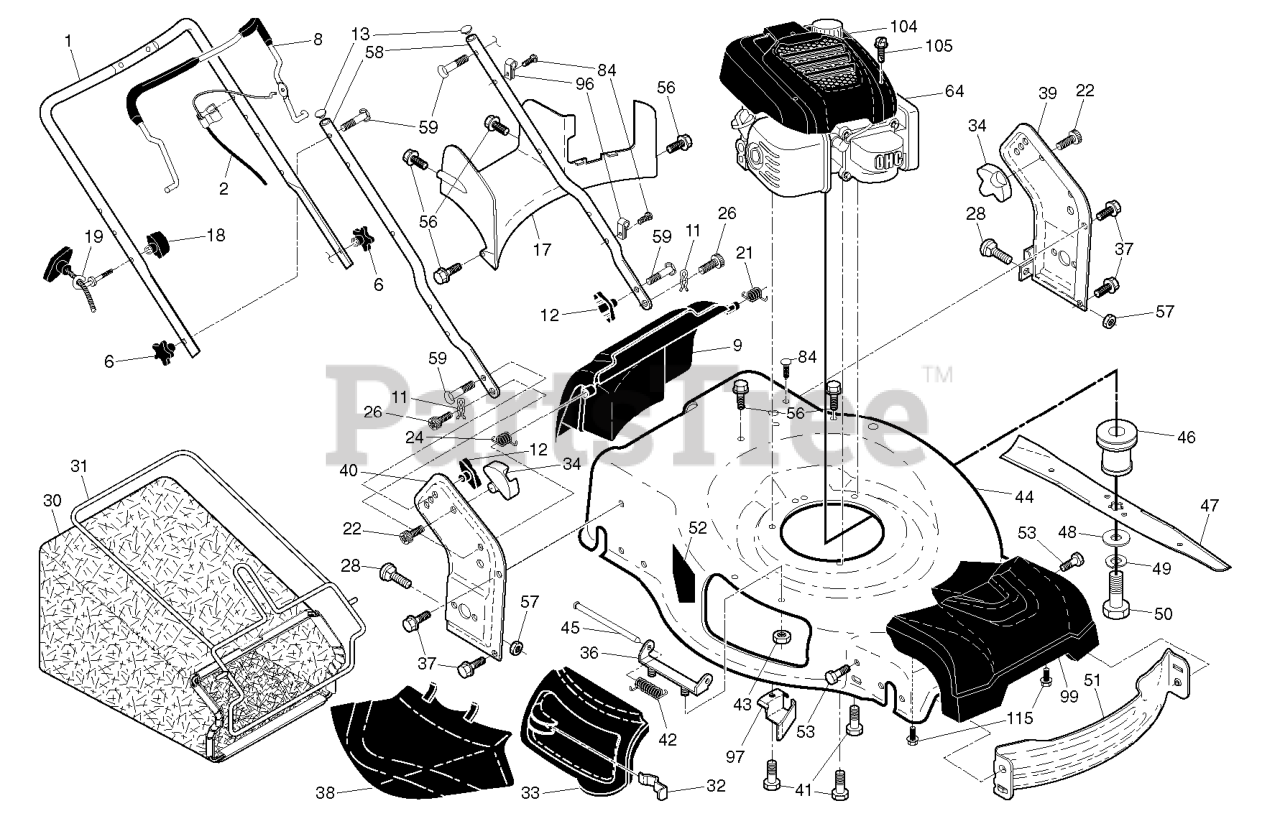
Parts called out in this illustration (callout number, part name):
1	HANDLE.UP.3POS.BS.AW2.GREY
2	CABLE.MZR.ZONE.CONTROL
6	KNOB.HANDLE.PLASTIC.STAR.BLACK
8	BAIL.OM.ERGO.BENT.MZR.ORAN.668
9	DOOR.REAR.ASM.22+.HUSQ.F/RG.CE
11	COTTER.HAIRPIN.DOOR/HANDLE.PIV
12	KNOB, DEFLECTOR
13	PLUG.PLASTIC.7/8".14-20.GAUGE
17	BAFFLE.REAR.22+RGD.AWD.PLASTIC
18	T-KNOB.NEW ROPE GUIDE
19	GUIDE.ROPE.BLK.ZINC.CHROM
21	SPRING.LH.BLACK
22	SCREW.PAN.HEAD.#10
24	SPRING.RH.GRAY
26	SCREW,DOOR/HANDLE.PIVOT
28	BOLT.CARRIAGE.LN.5/16-18X.5/8
30	GBAG.BA85028ER.GRY/ORG
31	FRAME.GBAG.22+.BLK
32	LATCH.DOOR.ZINC
33	DOOR.MULCH.22 PLUS.HUSQ.GREY
34	BRACKET.GRASSBAG.ATTACHING.BLK
36	BRACKET.ASM.HINGE.21.FWGD.
37	BOLT.5/16HEX.WHS.HD
38	DEFLECTOR.CLIPPING.22.BLACK
39	BRACKET.ASM.HANDLE.LT.22+.GREY
40	BRACKET.ASM.HANDLE.RT.22+.GREY
41	BOLT 3/8-16X1-1/8
42	SPRING.TORSION
43	NUT.FLANGE.1-4-20-SERR
44	HOUSING.22+RGD.MCUT.WO.HUS.TRI
45	ROD.HINGE.21
46	ADAPTER.BLADE.25MM.3MPH
47	BLADE.22+4N1.2PIN.5STAR.(P07)
48	WASHER,HARDEN
49	LOCKWASHER
50	SCREW, HEX HD 3/8-24 X 1-3/8
51	BAFFLE.FRONT.22.PLUS
52	DECAL.INTERNATIONL.CUTFINGER
53	BOLT.5/16HEX.WHS.HD
56	SCREW.HX.13X.750
57	NUT.FLANGE.5/16
58	HANDLE.LOWER.22+.BT.GRAY
59	BOLT, HANDLE 5/16-18X1.75
84	FASTENER.PUSH.O.250X0.783
96	CLIP.CABLE.BLK
97	BRACKET.BELT.GUIDE.22+.BZP
99	COVER.ASM.FRONT.HUSQ.22+RGD
104	SHROUD.ASM.HONDA.HUSQVARNA
105	SCREW.SHROUD.HONDA
115	SCREW.HI-LO. 5/16 X 1.00
